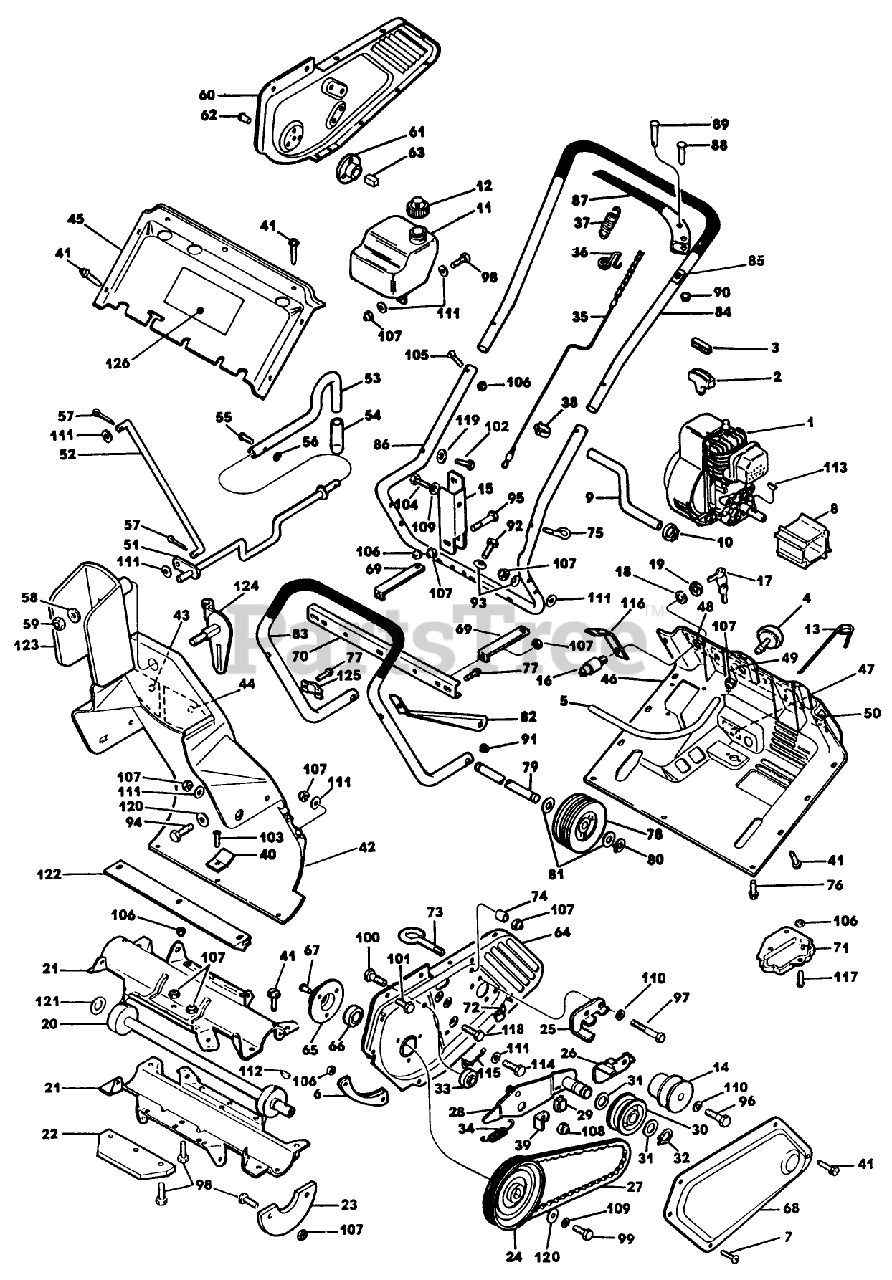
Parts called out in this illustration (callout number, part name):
1	**Engine-Tecumseh 3 H.P. **Engine-Tecumseh 3 H.P. Electric Start
1	**Engine-Tecumseh 3 H.P **Engine-Tecumseh 3 H.P. Electric Start
3	CLIP-STARTER
4	PRIMER ASSEMBLY
12	GAS CAP ASM
13	CHOKE WIRE ASM
14	ENGINE PULLEY
20	AUGER SUPPORT AY
21	PLATE-AUGER
22	IMPELLER TIP
23	FLIGHT
24	DRIVE PULLEY AY
25	UPPER BELT GUIDE
26	LOWER BELT GUIDE
27	V-BELT (207159)
28	IDLER ARM ASM
29	SKID BLOCK
31	WASHER
34	BRAKE SPRING
36	CLIP CABLE
37	SPRING - CLUTCH
46	BOTTOM COVER&DECAL
52	CONTROL LINK
59	NUT
66	BEARING - BALL
68	COVER - BELT *B
71	START BLOCK SPACER
77	SCREW
80	SNAP RING
86	FRAME TUBE
87	LEVER ASM
89	PIN-CLEVIS
100	SCREW
103	SCREW
106	NUT E
107	NUT-LOCK, CONE
108	NUT
115	FINGER BELT
117	SCREW - PPH
123	VANE-DEFLECTOR
